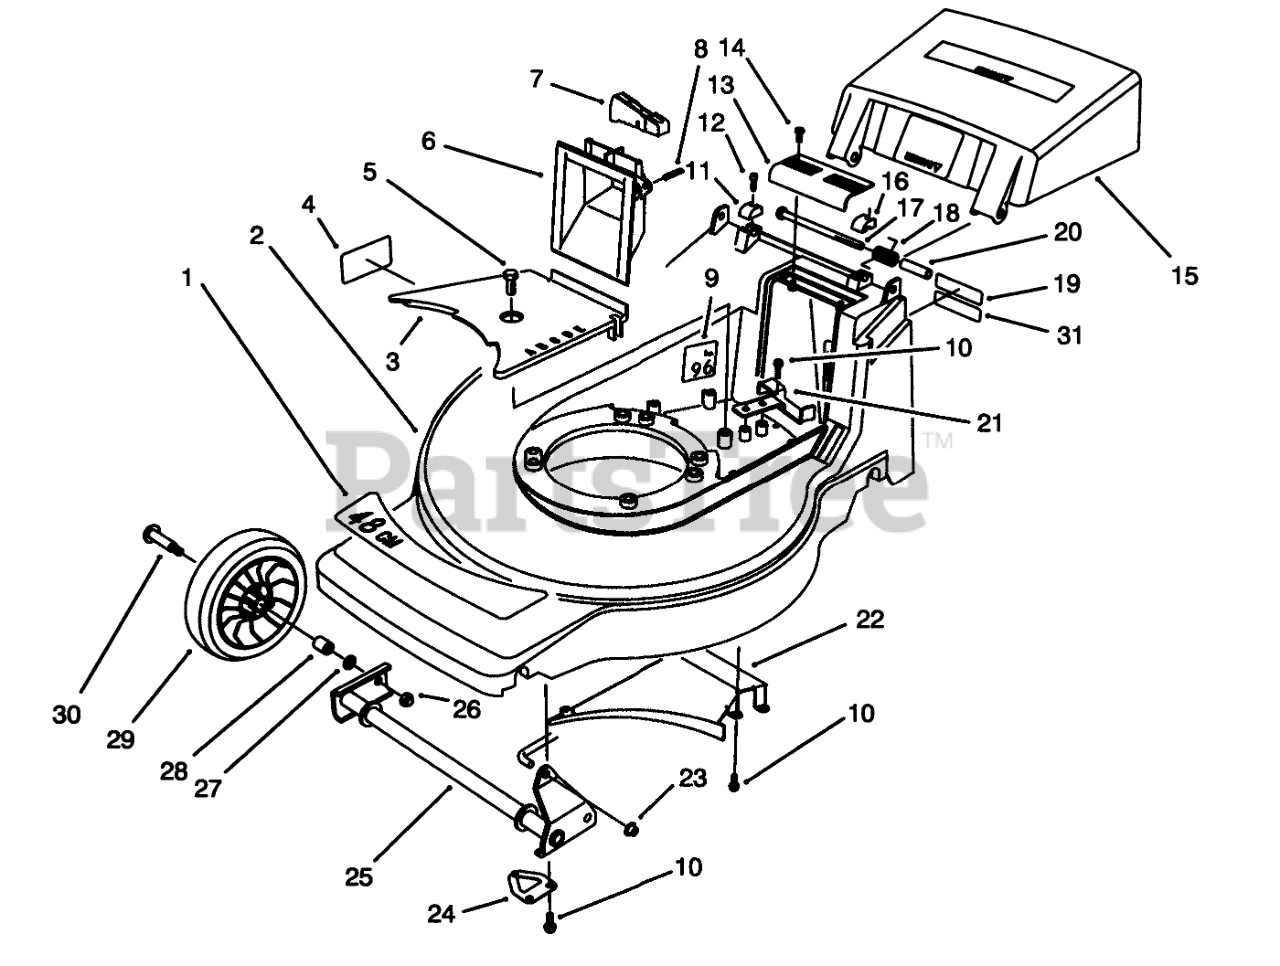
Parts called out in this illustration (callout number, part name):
1	DECAL - DECK 48 CM
2	Housing-48cm (Incl. Ref. #4)
3	BELT COVER
4	Decal Danger
5	SCREW-HWHTF
6	GRIP - LOWER
7	TRIGGER - HOC
8	PIN-SPIRAL
9	Decal-Noise Rating
10	SCREW-HWH
11	CAP-HINGE BOLT, RH
12	SCREW-HSH
13	GRIP-UPPER
14	SCREW-PPH, PLASTITE
15	Door Discharge
16	CAP-HINGE BOLT, LH
17	SCREW-HH
18	SPRING-DOOR
19	DECAL FRENCH REGUL.
20	SPACER-DOOR
21	REAR BELT GUIDE
22	Ramp-Discharge
23	NUT-PUSH
24	SHAFT RETAINER ASM
25	FRONT PIVOT WA
26	NUT-HEX
27	WASHER
28	BUSHING
29	Wheel & Tire Assembly (Incl. Ref. #28)
30	BOLT-WHEEL
31	Decal-Power Rating
